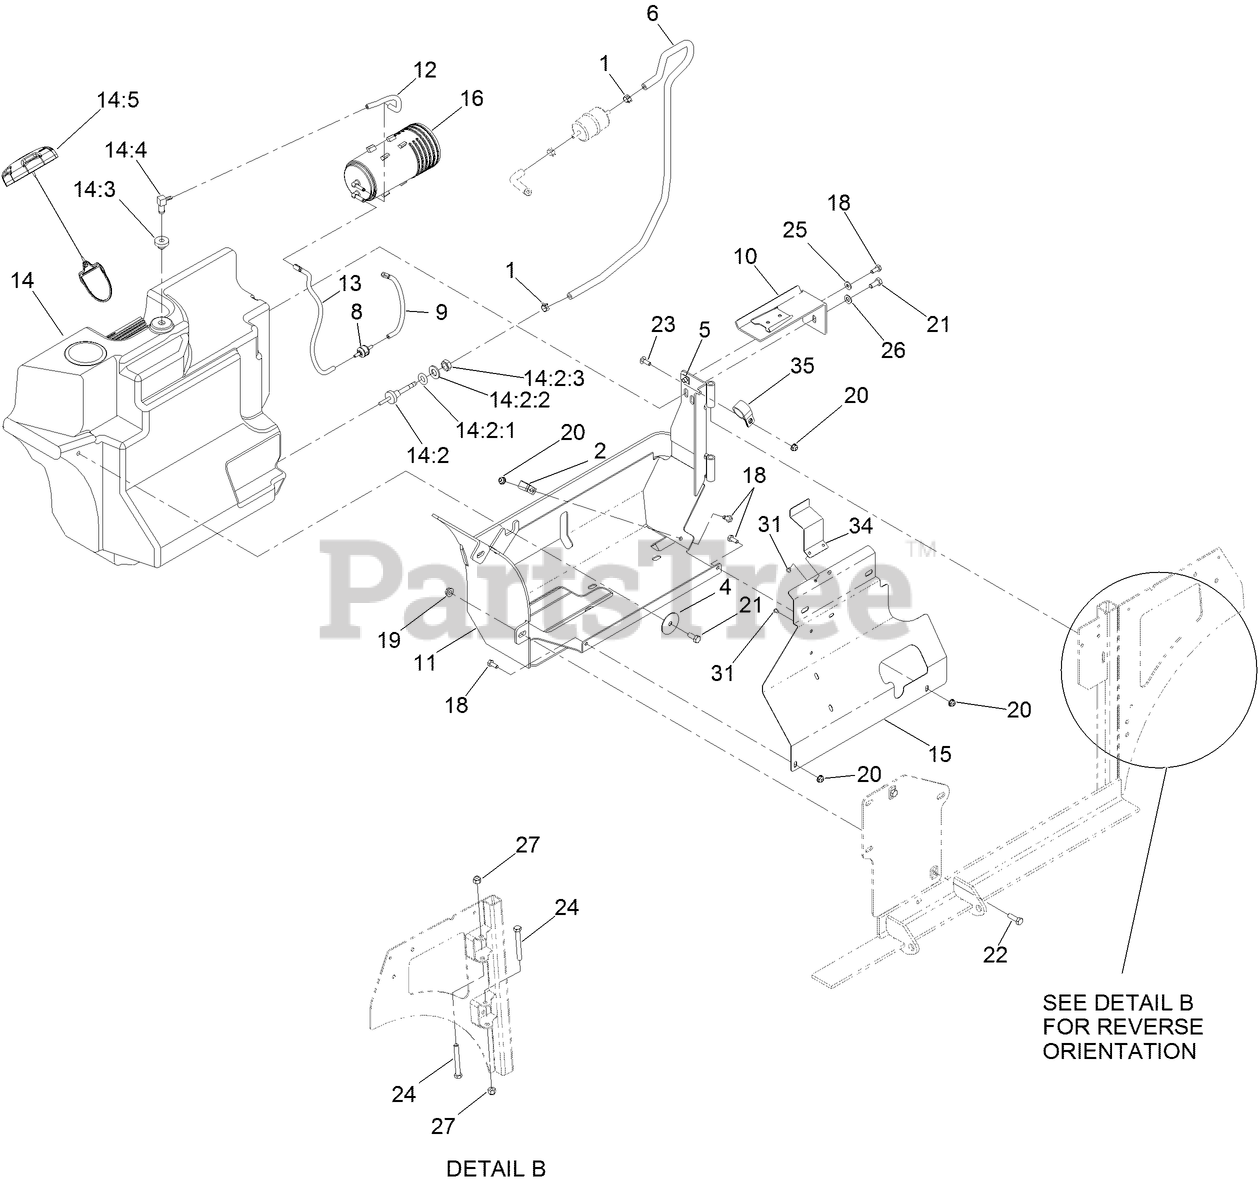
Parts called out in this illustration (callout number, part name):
1	CLAMP-HOSE
2	CLIP-LOOM
4	WASHER
6	HOSE-FUEL
8	VALVE-CHECK, VACUUM
9	HOSE-VENT, FORMED
10	CANISTER BRACKET ASM
11	TANK FRAME ASM
12	HOSE-VENT, FORMED
13	HOSE-VENT, FORMED
14	FUEL TANK ASM
14:2	FITTING-FUEL, BULKHEAD
14:2:1	O-RING,BULKHEAD FITTING
14:2:2	WASHER-FLAT
14:2:3	NUT-JAM
14:3	BUSHING
15	PANEL-TANK SHIELD
16	CANISTER-CARBON, 800CC
18	SCREW-HH
19	NUT-HF
20	NUT-HF
21	SCREW-HH
22	SCREW-HH
23	BOLT-CARR
24	SCREW-HH
25	WASHER-FLAT
26	WASHER-PLAIN
27	NUT-LOCK, NI
31	RIVET-POP
34	BRACKET-SHIELD, TANK
35	R-CLAMP
